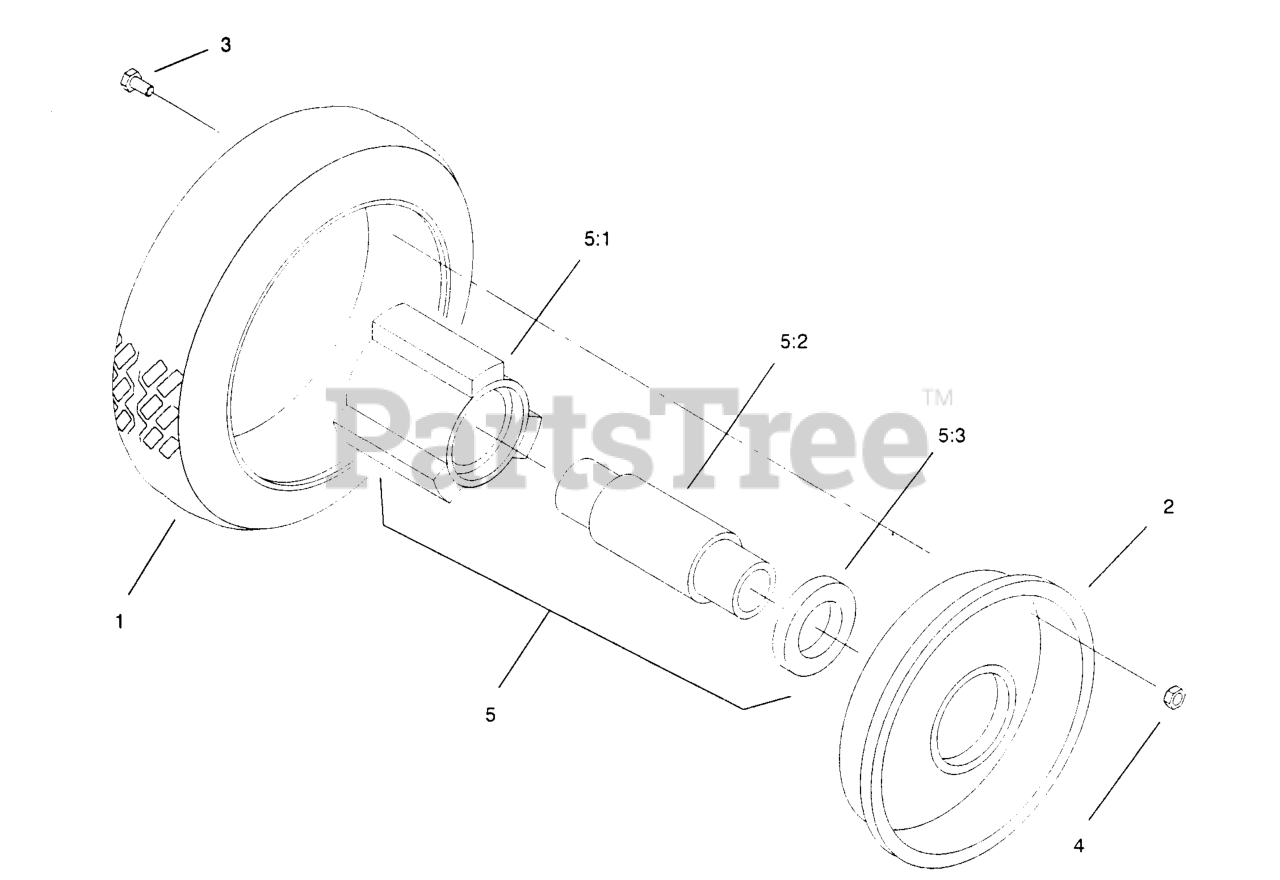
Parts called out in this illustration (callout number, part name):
3	SCREW-HH
4	NUT-LOCK, NI
5	Hub & Bearing Asm
5:1	HUB-BEARING
5:2	SPACER-BEARING
5:3	BEARING-WHEEL
